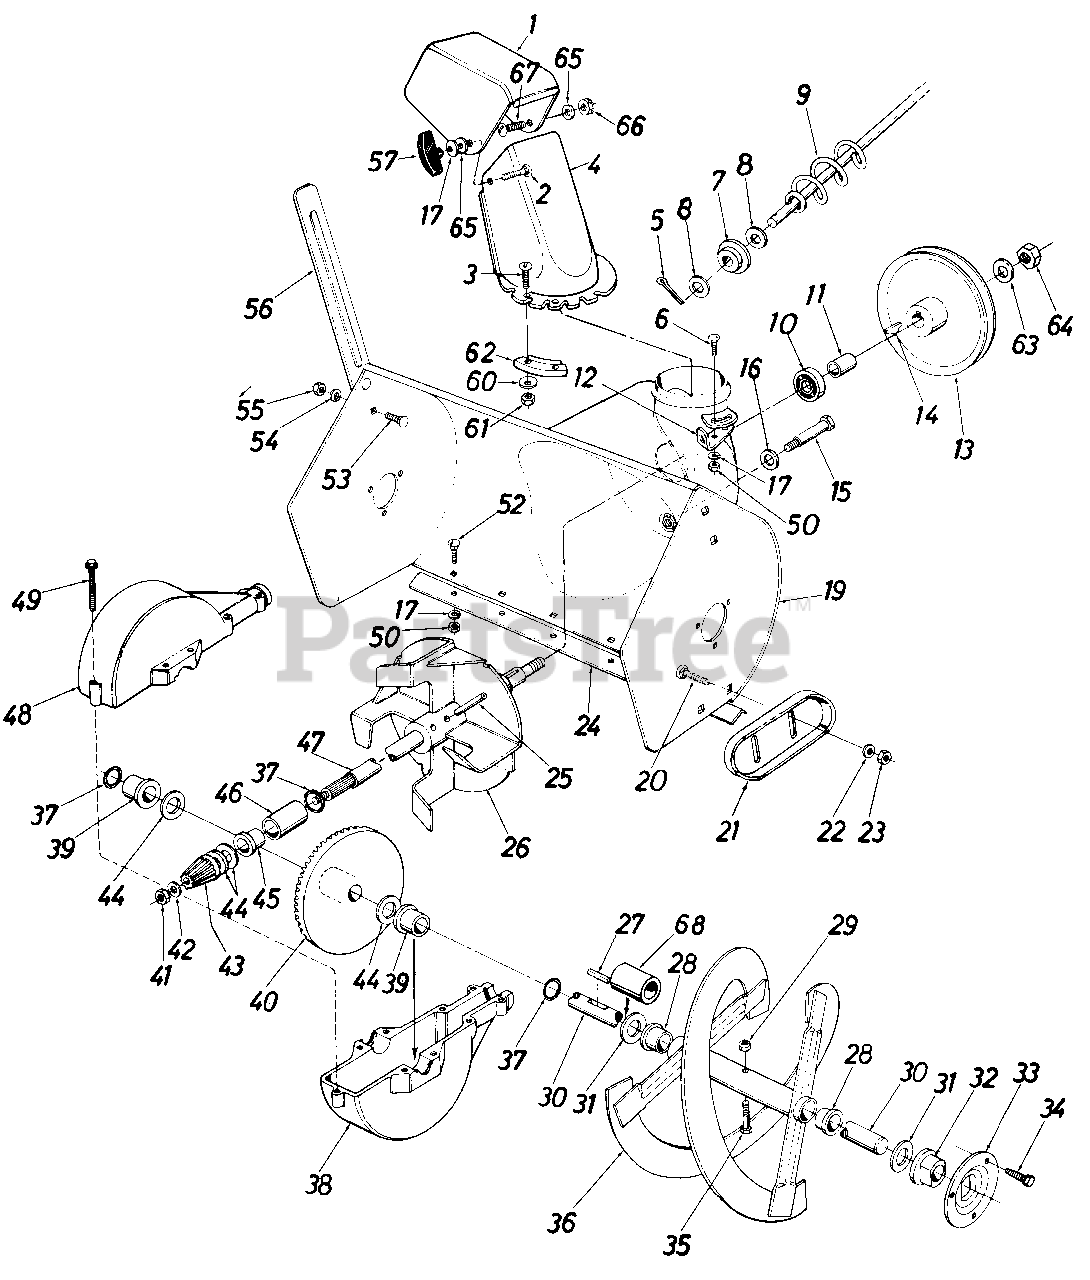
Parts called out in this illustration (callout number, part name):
1	Upper Chute
2	Carriage Bolt 5/16-18 x 1.0"
3	Truss Mach. Scr. 1/4-20 x .751'
4	Lower Chute
5	Cotter Pin
6	Carriage Bolt 5/16-18 x .751'
7	Bushing
8	Fl-Wash. .385 I.D. x .62" O.D.
9	Chute Crank Ass'y.
10	Ball Brg. .62" I.D. x 1.38" O.D.
11	Spacer .63" I.D. x .88" O.D. x .900" Lg.
13	1/2" "V"-Pulley .625" I.D. x 7.50" O.D. (420 & 524)
14	#61 Hi-Pro Key 3116" x 518" Dia.
15	Shld. Bolt .50" Dia. x 2.11"
16	Bell-Wash. .40" I.D. x .88" O.D. x .06
17	Bell-Wash. .34" I.D. x .88" O.D.
20	Carriage Bolt 3/8-16 x .62"
21	Slide Shoe
22	Bell-Wash. 318" I.D.
23	Hex Jam Nut 3/8-16 Thd.
24	20" Shave Plate (420)
26	11" Dia. Blower Fan Ass'y.
27	Sq. Key 3/16" x 1.5" Lg.
28	Flange Brg. .75" I.D. x .88" O.D.
29	Hex Ins. L-Nut 5/16-18
30	Spiral Axle (420)
31	Fl-Wash. .75" I.D. x 1.50" O.D. x .06
32	Flange Brg. w/Flats .755" I.D.
33	Bearing Housing
34	Hex Wash. Hd. Self-Tap Scr.5/16-24 x .62" Lg.
35	Hex Bolt 5/16-18 x 1.50" Lg.
36	20" Spiral Ass'y.-L.H. (420)
37	"O"-Ring-3/4" I.D.
38	Bevel Gear Housing-Lower Half
39	Plastic Flange Brg. .755" I.D.
40	Bevel Gear
41	Hex Cent. L-Nut 5/16-24 Thd.
42	Fl-Wash. .34" I.D. x .62" O.D. x .06
43	Pinion Gear
44	Fl-Wash. .75" I.D. x 1.25" O.D. x .06
45	Flange Brg. .755" I.D.
46	Sleeve Brg. .755" I.D.
47	Blower Axle
48	Bevel Gear Housing- Upper Half
49	Hex Wash. Hd. Self-Tap Scr. 1/4-20 x 1.00" Lg.
50	Hex Nut 5/16-18 Thd.
52	Carriage Bolt 5/16-18 x .62" Lg.
53	Carriage Bolt 5/16-18 x .62" Lg.
54	L-Wash. 5/16" I.D.
55	Hex Nut 5/16-18 Thd.
56	Drift Cutter Bar
57	Knob
60	Fl-Wash. 1/4" I.D.
61	Hex L-Nut 1/4-20 Thd.
62	Chute Flange Keeper
63	Fl-Wash. .64" I.D. x .94" O.D. x .06
64	Hex Jam Nut 5/8-18 Thd.
65	Fl-Wash. .344 I.D. x 1.125 O.D.
66	Hex L-Nut 5/16-18 Thd.
67	Truss Mach. Scr. 5/16-18 x .75" Lg.
68	Spacer (826)
